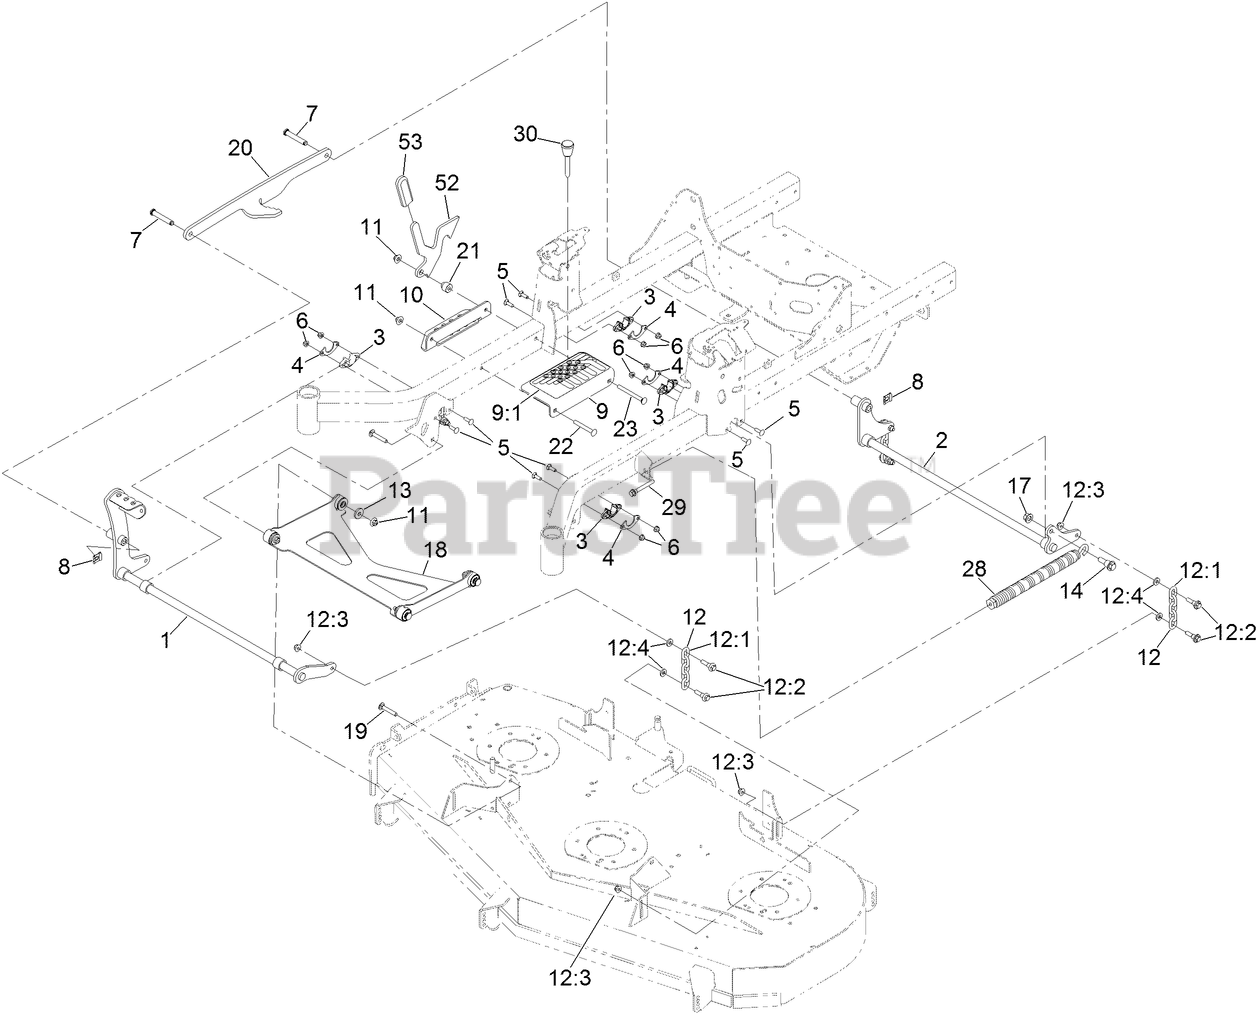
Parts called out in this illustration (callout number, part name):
1	SHAFT-LIFT, DECK
2	SHAFT-LIFT, DECK (REAR)
3	BUSHING-FLANGE
4	GUSSET-LIFT, DECK
5	SCREW-CARR
6	NUT-HF, NI
7	PIN-CLEVIS
8	CLIP-PIN
9	BRACKET ASM
9:1	DECAL-HOC
10	ANGLE-HOC, LOWER
11	NUT-FLANGE, NI
12	DECK CHAIN ASM
12:1	CHAIN-LIFT, DECK
12:2	BOLT-SHOULDER
12:3	NUT-HF, NI
12:4	SPACER
13	WASHER
14	SCREW-SHOULDER, HHF
17	NUT-LOCK
18	DECK STRUT ASM
19	SCREW-CARR
20	LINK-LIFT
21	SPACER-STEPPED
22	SCREW-CARR
23	SCREW-CARR
28	SPRING-EXTENSION
29	BOLT-SHOULDER
30	PIN-HOC
52	PLATE-TRANSPORT LOCK
53	GRIP-LEVER
